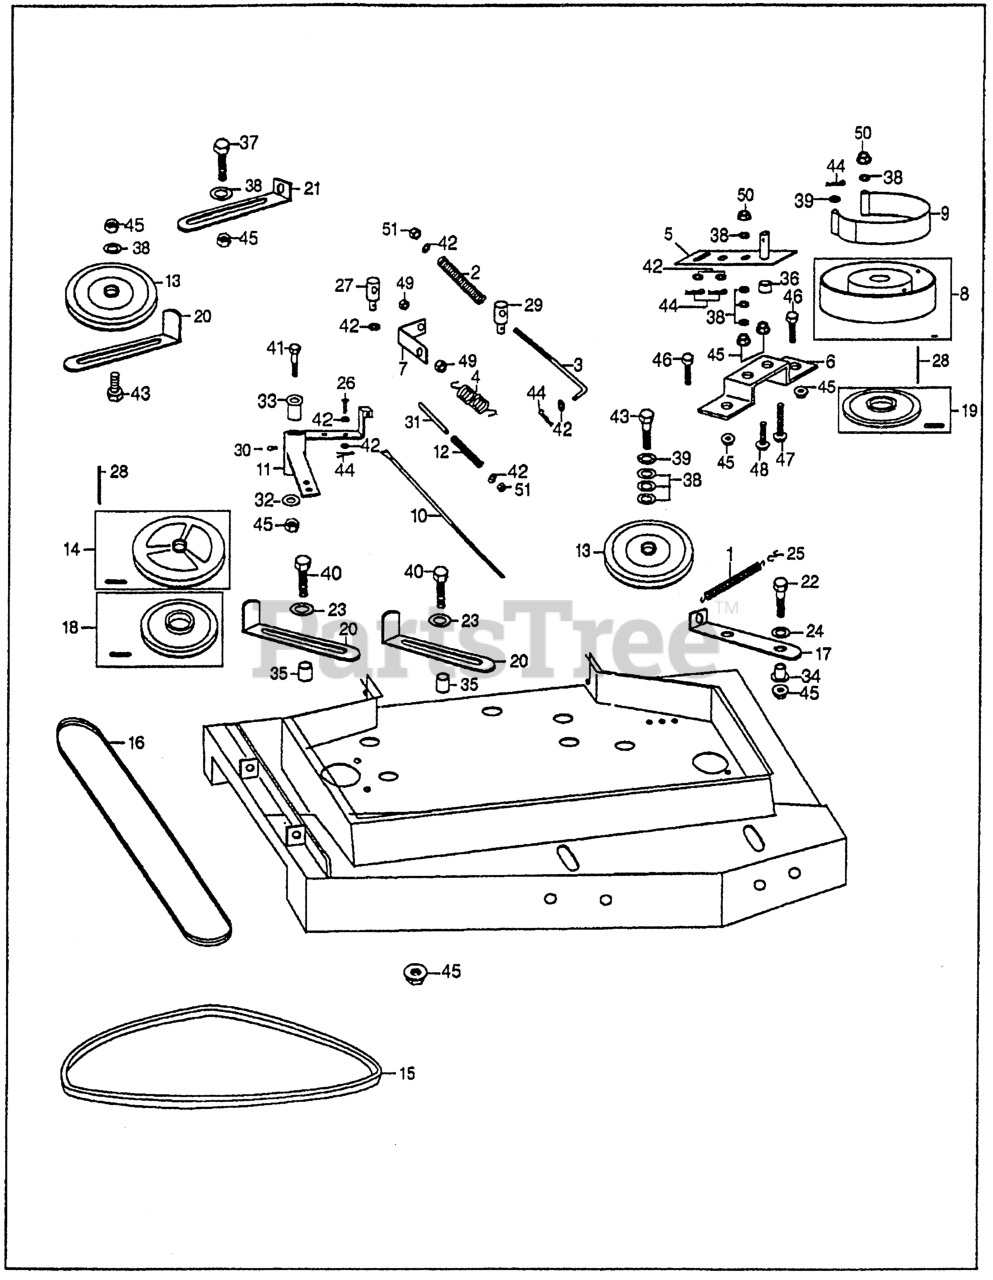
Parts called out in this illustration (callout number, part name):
1	SPRING, TENSIONER
2	SPRING, NEUTRAL Use up to Frame SN 1000677.
3	ROD, NEUTRAL
4	SPRING, PUMP ARM
5	ARM, BRAKE
6	PLATE, BRAKE (NOT AVAILABLE)
7	BRACKET, SPRING
8	DISK, FRICTION
9	BAND, BRAKE
10	ROD C, P.T.O. (36")
11	ARM, TENSIONER
12	SPRING, TENSIONER ARM Use up to Frame SN 1000677.
13	PULLEY A, TENSION
14	KIT, DECK PULLEY
15	V-BELT, BLADE
16	V-BELT, DECK Use up to Frame SN 1000677.
17	ARM, IDLER
18	PULLEY KIT A
19	PULLEY KIT B
20	GUIDE A, BELT
21	GUIDE B, BELT
22	BOLT A, SHOULDER
23	WASHER
24	WASHER, BELLEVILLE (1/2") Use up to Frame SN 1000677.
25	CLIP, SPRING
26	PIN, PIVOT
27	PIN, CLEVIS (5/16")
28	KEY, SQUARE (1/4"X1/4"X1")
29	PIN, SWIVEL
30	NIPPLE, GREASE
31	TUBE, VINYL (7/16"X2) (1/2")
32	BUSHING (1")
33	BUSHING, PIVOT
34	BUSHING, SNAP
35	COLLAR B, SPACER
36	COLLAR, BRAKE
